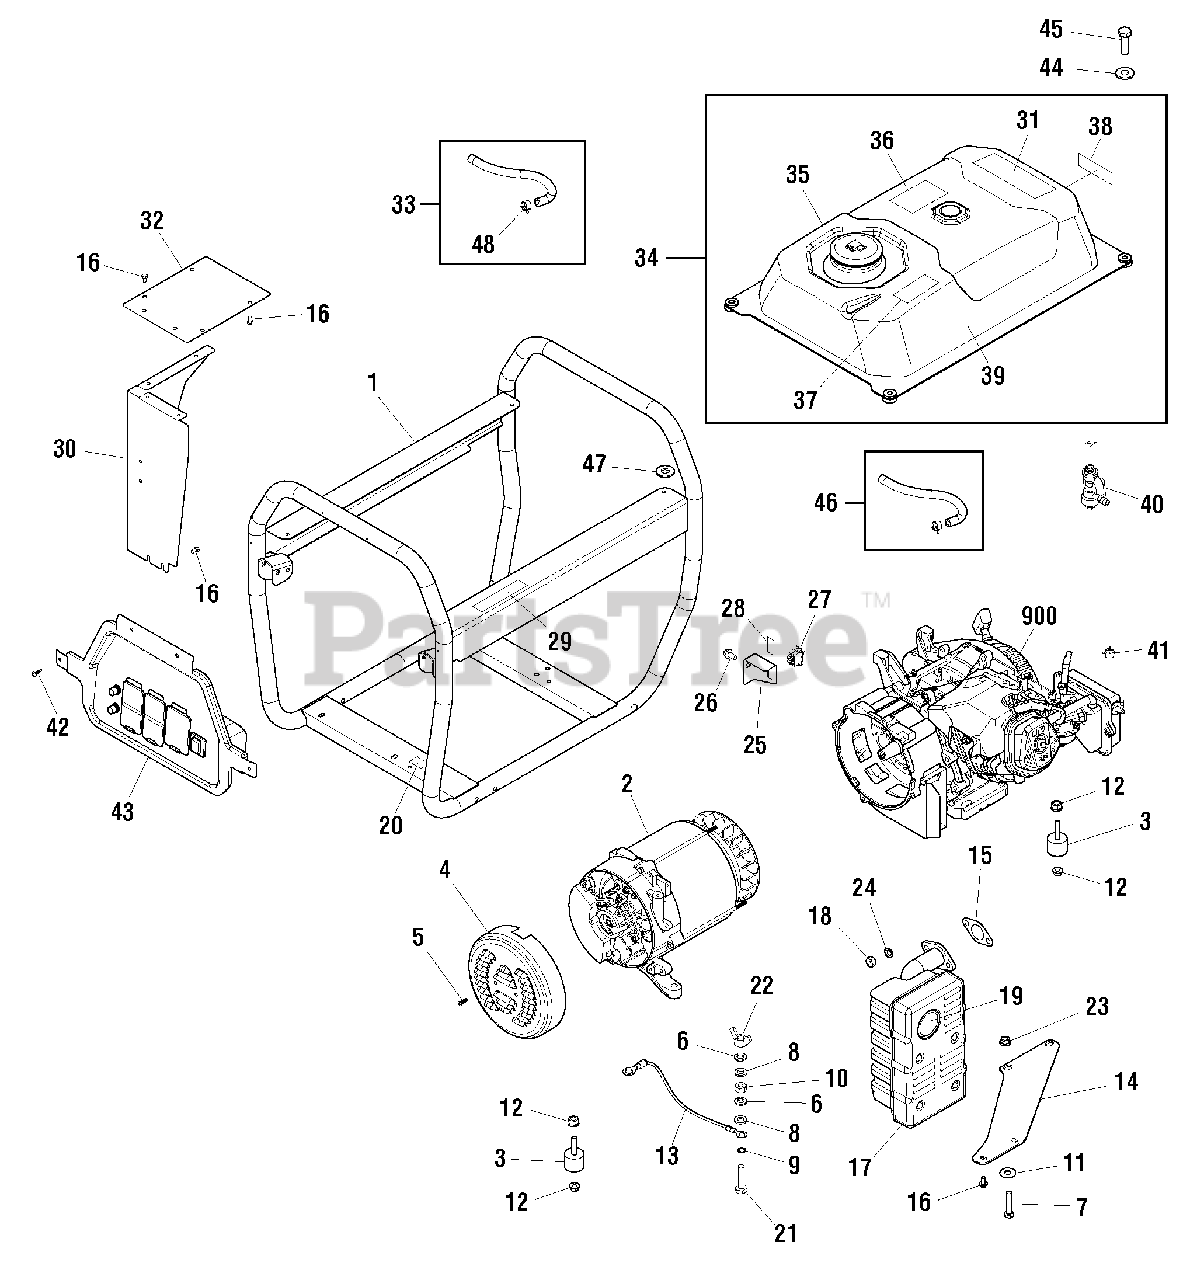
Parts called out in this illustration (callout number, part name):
1	CRADLE (Includes Item 20 & 29)
2	ALTERNATOR
3	MOUNT-VIBRATION
4	COVER-REAR BEARING
6	* WASHER, Lock, 1/4
7	* CAPSCREW, Hex Head, M10-1.5 x 45
8	* WASHER, Flat, M6
10	* NUT, Hex, M6-1.0
11	WASHER
16	* CAPSCREW, Hex Head, M6 - 1.0 x 10
18	* NUT, Hex, M8 1.25
21	* CAPSCREW, Hex Head, M6 - 1.0 x 25
23	* NUT, Lock, M10
24	* WASHER, Lock, 3/8
26	* SCREW, Flange, M8-10
27	SWITCH-ROCKER
43	PANEL-CONTROL
46	KIT-FUEL HOSE (Cut to fit)
48	CLAMP
900	** ENGINE
